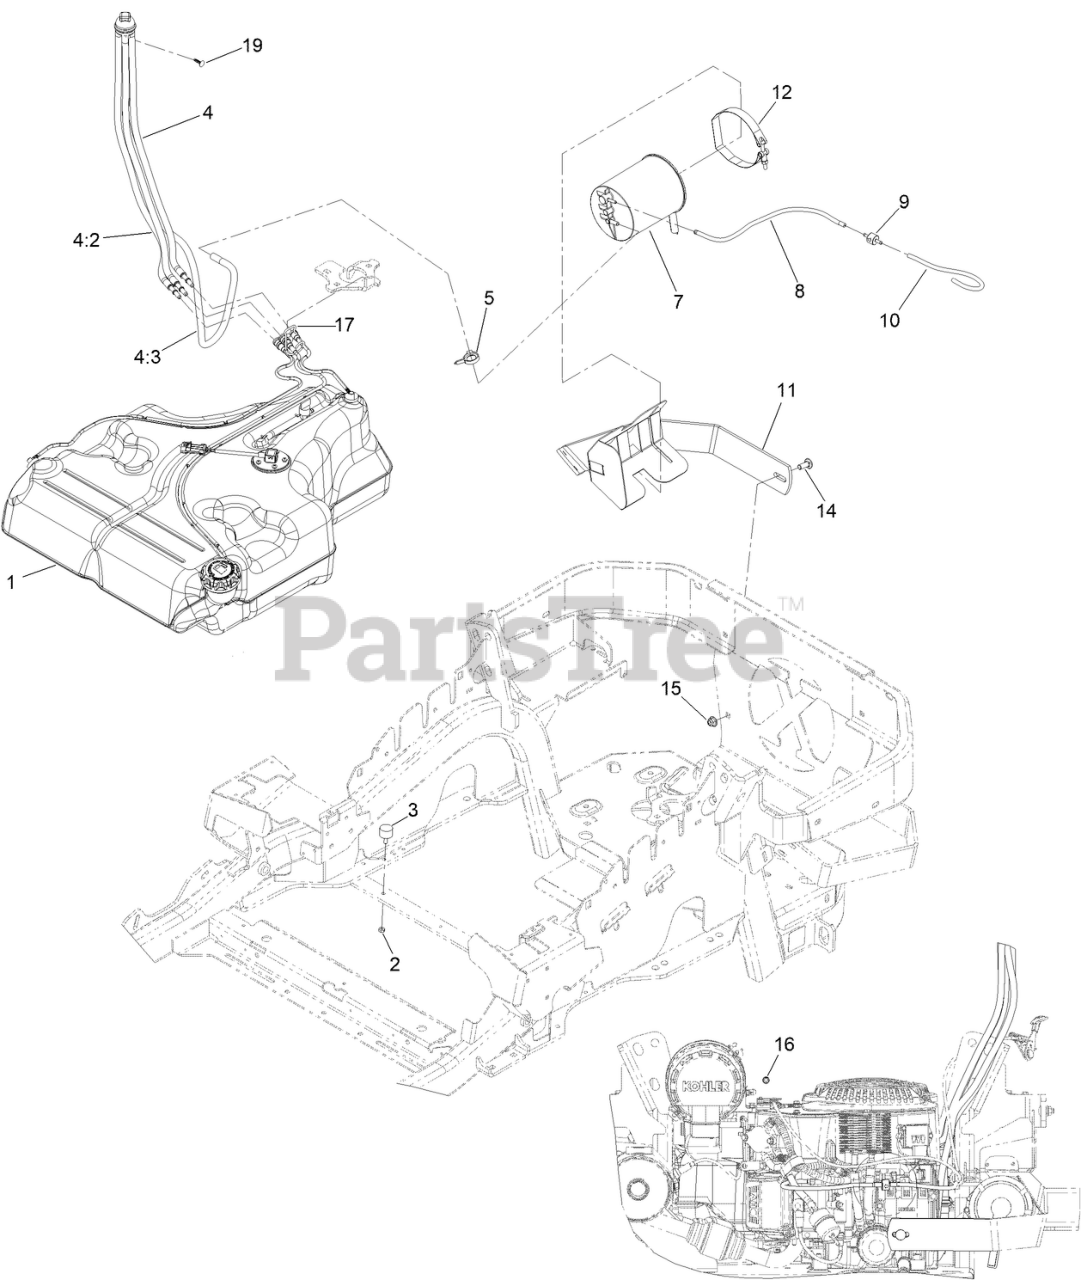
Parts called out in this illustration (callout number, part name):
1	FUEL TANK ASM
2	NUT-JAM
3	BUMPER
4	FUEL MANIFOLD VENT ASM
4:2	HOSE-FUEL
4:3	HOSE-FUEL
5	CLAMP-HOSE
7	CANISTER-CARBON, 1200CC
8	HOSE-VENT, FORMED
9	VALVE-CHECK, VACUUM
10	HOSE-VENT, FORMED
11	MOUNT-CANISTER
12	CLAMP, T-BOLT
14	SCREW-CARR
15	NUT-HF, NI
16	PLUG-PORT
17	RETAINER-LINE, VAPOR
19	PLUG-PLASTIC
